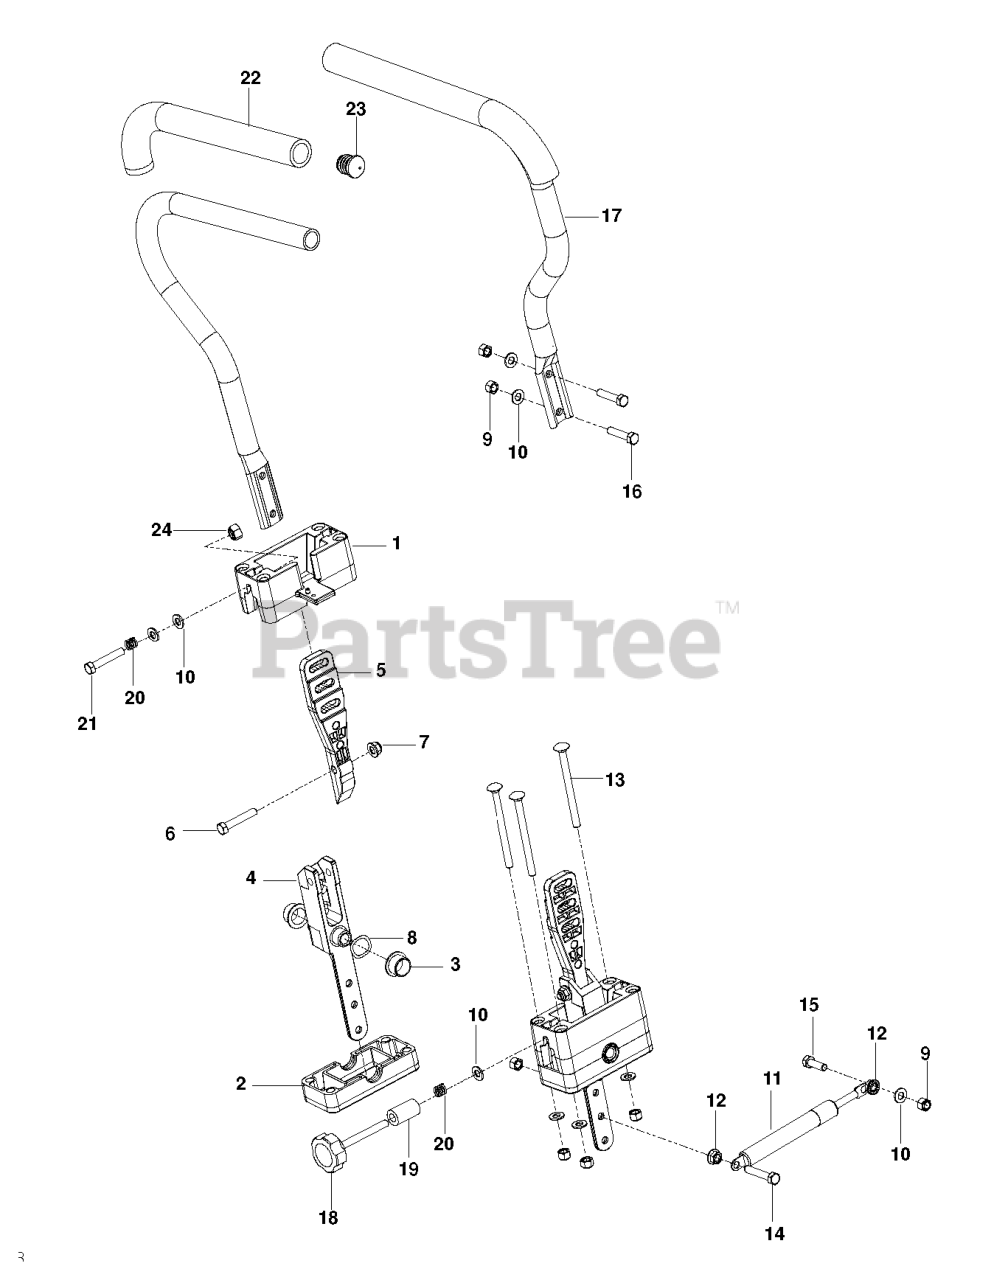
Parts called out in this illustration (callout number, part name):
1	BLOCK, UPPER
2	BLOCK, LOWER
3	BEARING, FLANGE
4	PIVOT.SECTION.DRIVE.CONTROL
5	MOUNT, DR CNTRL HANDLE
6	HCS 5/16C X 1 3/4
7	5/16-18 NYLOC FLANGE NUT
8	WASHER, .825 X 1.087, WAVE
9	NUT 5/16 NYLOC
10	FLAT WASHER 5/16 SAE
12	NUT 5/16C WHIZ
13	RHSNB 5/16-18 X 4 GR 5 ZD
14	HCS 5/16-18X1-3/4 TPBLT
15	HCS 5/16C X 1
16	CAPSCREW 5/16 X 1/1/2 HEX HEAD
17	LEVER.DRIVE.W/GRIP
21	HCS 5/16-18 X 2 TPBLT GR 5 ZD
22	GRIP, FOAM (GROUND) 15
23	END PLUG 15/16 (BLACK)
24	NUT 5/16C HEX
